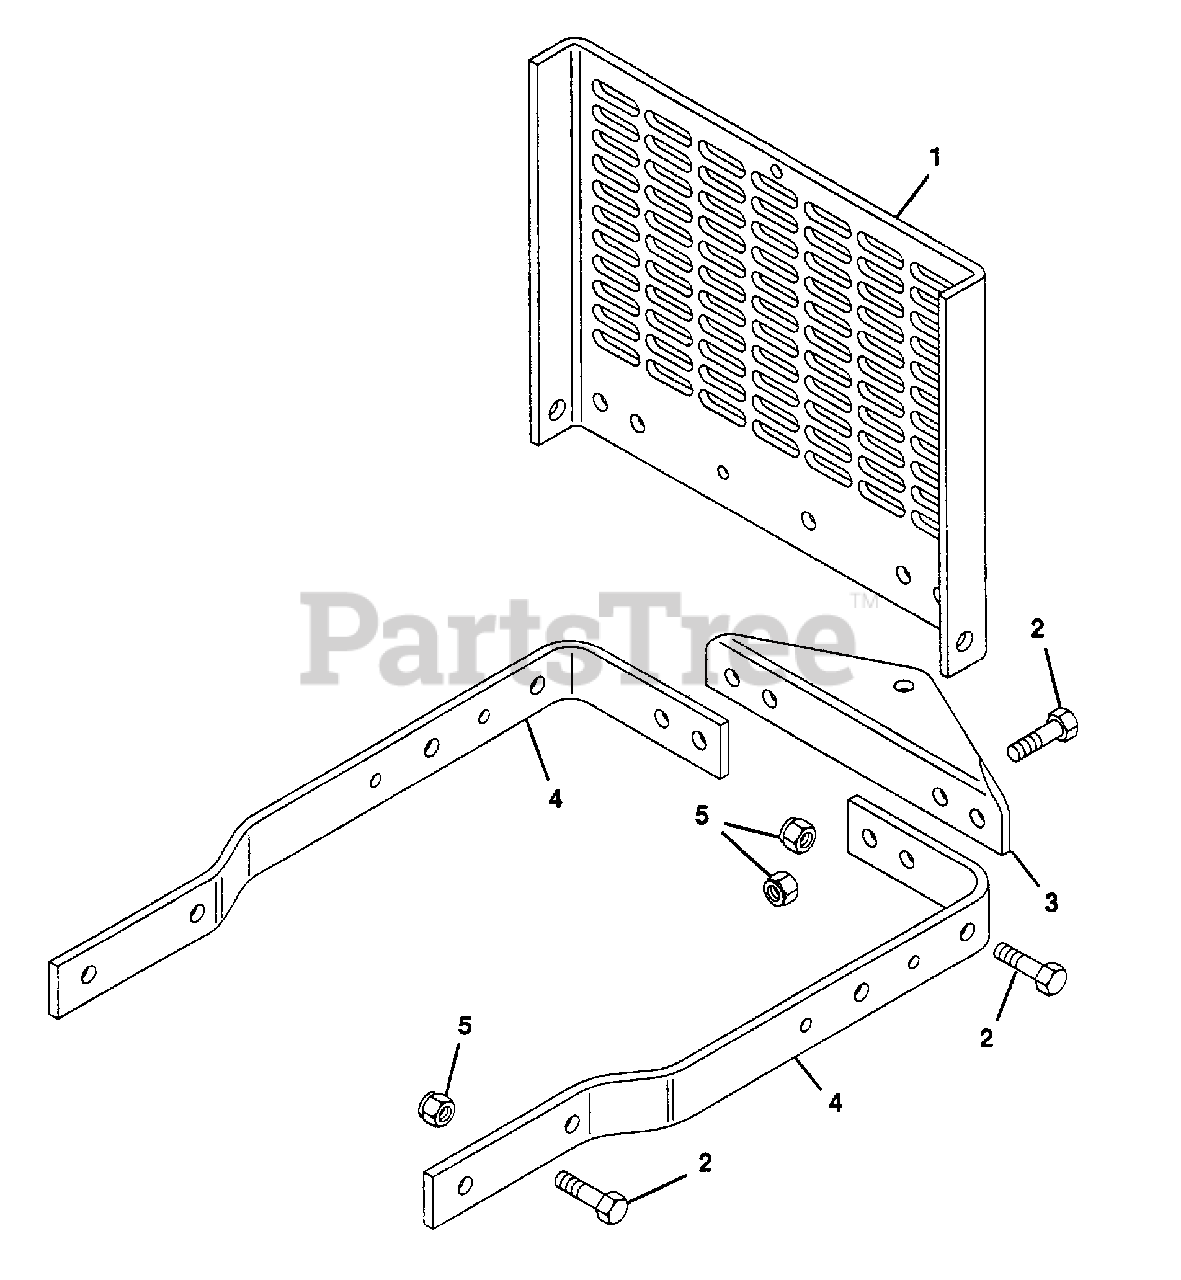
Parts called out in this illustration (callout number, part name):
1	GUARD, ENGINE
2	BOLT, HEX 1/2-13X1.75
3	PLATE, HITCH
4	ARM, REAR HITCH
5	NUT, LOCK 1/2-13
